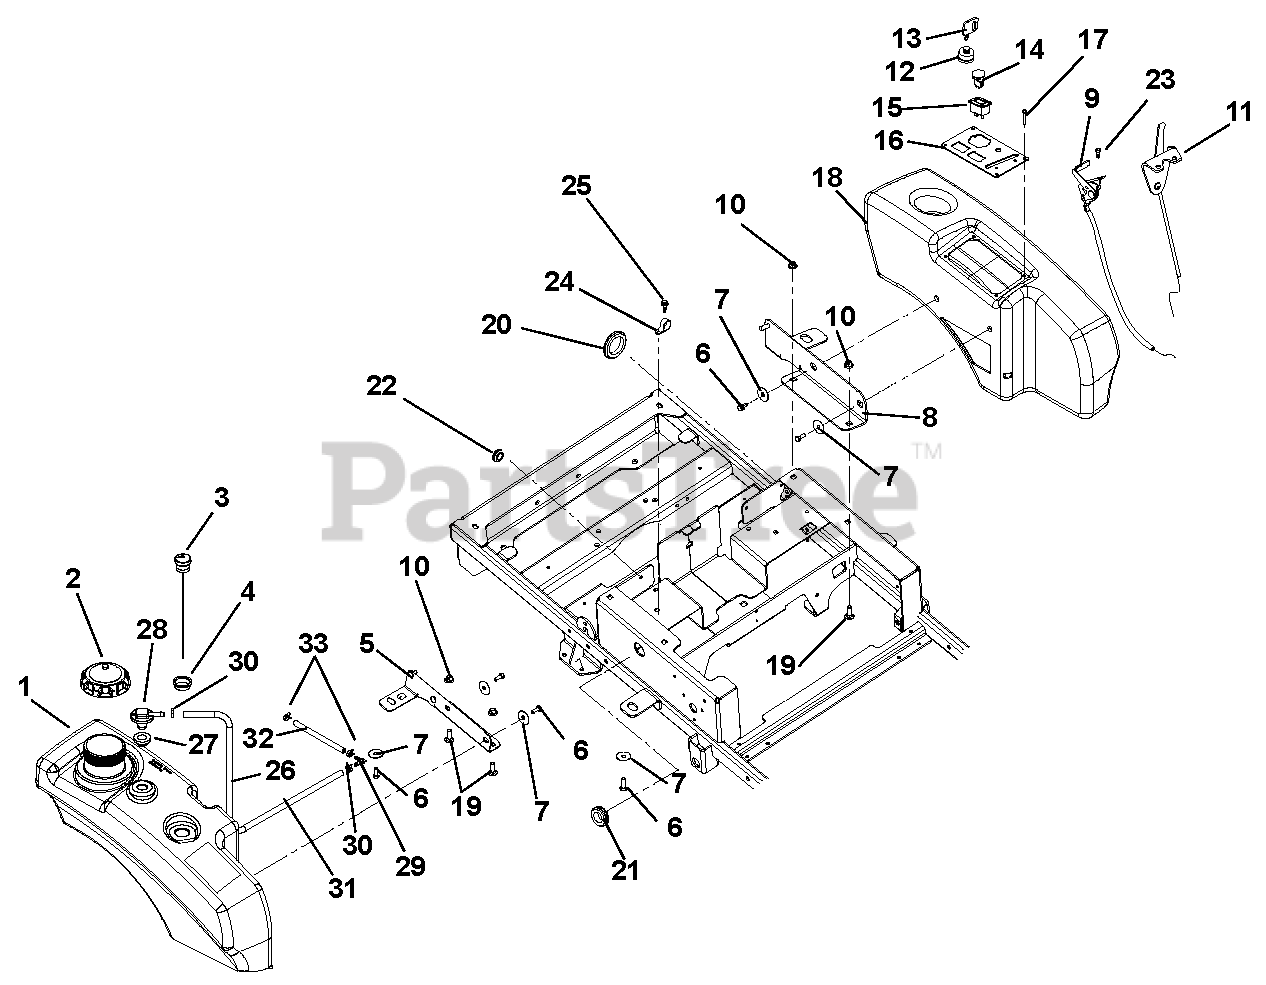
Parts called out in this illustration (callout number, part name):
1	Tank, XL Non-Permeable Fuel
2	Cap, Fuel Vent-in Autolock
3	Gauge, Remote Fuel 10.0"
4	Grommet, Fuel Gauge
5	Weldment, RH Tank Mount
6	Bolt, Serrated Hex Flange Washer
7	Washer, Flat Steel .347 x 1.254 x
8	Weldment, LH Fender Mount
9	Cable, Throttle
10	Nut, .38-16 Nyloc Flange
11	Cable, Choke
12	Key Switch
13	Key, w/Cap
14	Switch, Clutch
15	Hour Meter, Digital
16	Panel, Control
17	Screw, Hex .25 x 14-.75
18	Fender, XL
19	Bolt, Round Head Square Neck .38-
20	Grommet, 2.00"
21	Grommet .125 x 1.000 ID
22	Grommet, Rubber 5/8 ID/1.13 OD
23	Screw, Tapping 10-24 x .50 Hex Wa
24	Clamp, Cushioned Steel
25	Screw, Tap Hex Washer Head .38-16
26	Tube, Fuel Pick-up (XL)
27	Grommet, Remote Vent, Nitrile
28	Vent, Roll-over (.25" ID hose)
29	Fitting, 3/16 x 1/4 90 Degree VAC
30	Clamp, Fuel Line
31	Hose, .25 Low-Perm Bulk Gas
32	Hose, .188 Low-Perm Bulk Gas
33	Clamp, Hose, Spring .188
